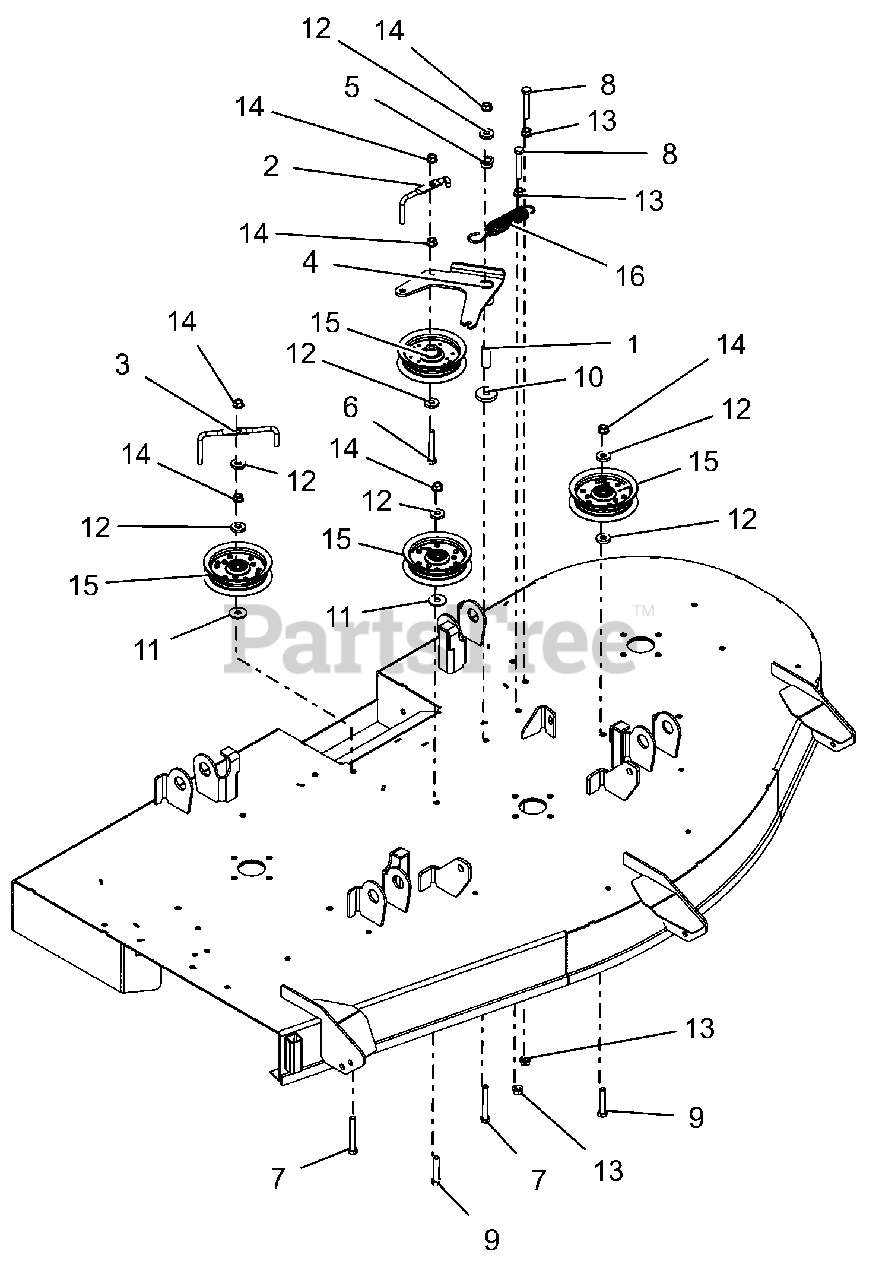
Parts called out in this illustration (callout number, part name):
1	SPACER, .375IDX.625ODX1.66 PM
2	WIREFORM, BELT FINGER
3	BELT FINGER
4	WLDMT, IDLER ARM-42"
5	BSHG-FLG, .625X.750X.500X1.00
6	@BLT-HEX .38-16X2.50 GR5 YWZC
7	@BLT-HEX .38-16X2.75 GR5 YWZC
8	@BLT-HEX .38-16X2.25 GR5 YWZC
9	@BLT-HEX .38-16X2.00 GR5 YWZC
10	WSHR,FLT STL.406X1.50X.245YWZC
11	WSHR-FL-STL .406X1.25X.10 ZC
12	WSHR-FL-STL .406X1.00X.188 YWZ
13	@NUT-SPNLK-FLG .375-16 YWZC
14	@NUT-LK-TOP-FLG .38-16 YWZC
15	ASM, IDLER 4"
16	SG-TENS .135X.98X6.0 WLD 62
